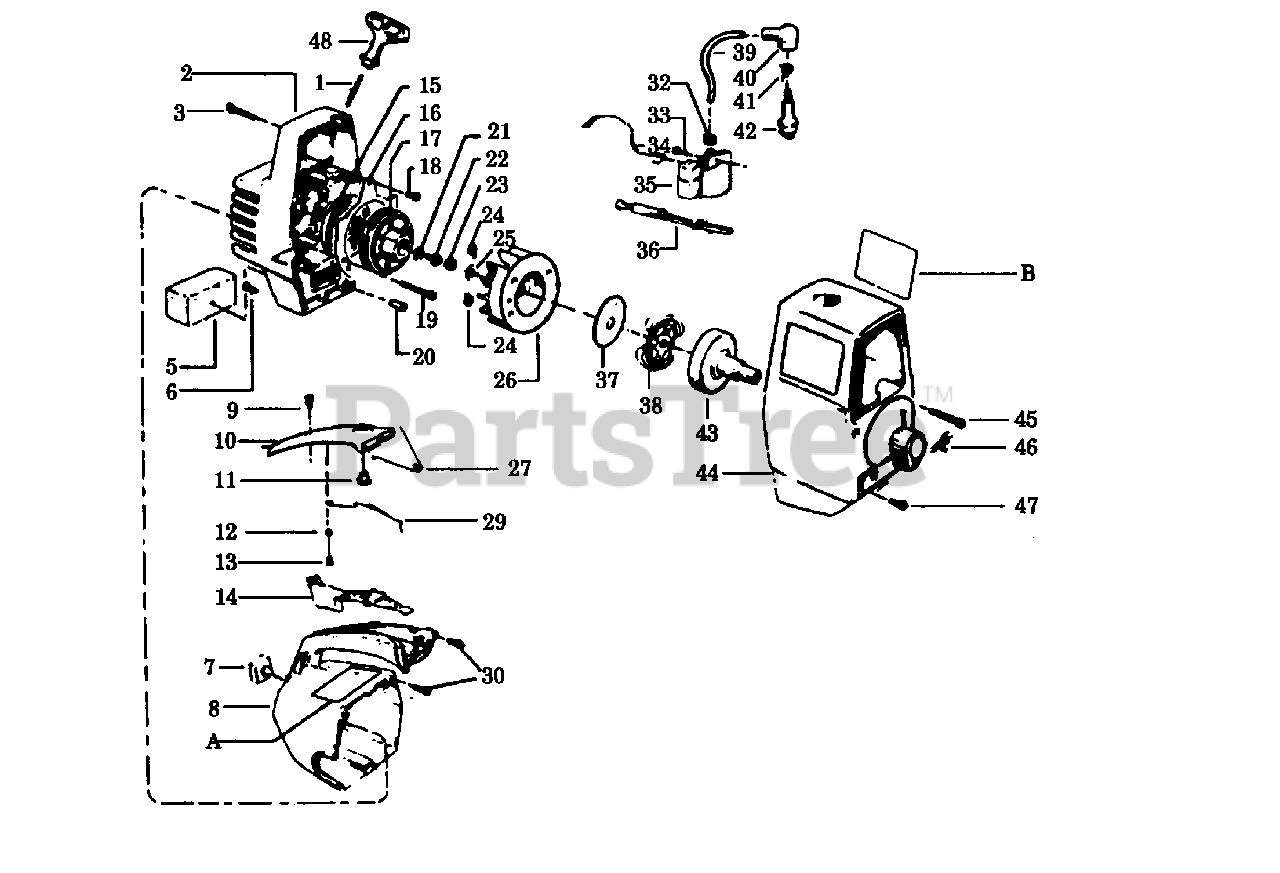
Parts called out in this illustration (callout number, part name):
1	Rope Kit
2	Fan Housing Kit
5	Air Filter
7	Fuel Tank Housing Bumper
8	Handle & Fuel Tank Housing
10	Handle Cover
11	Switch Button
12	Switch Washer
14	Throttle Trigger
15	Recoil Spring Starter
16	Air Baffle
17	Starter Pulley
20	Air Baffle Spacer
22	Screw
23	Flywheel Nut
24	Starter Dog Spring
26	Flywheel Ass'y.
27	Trigger Spring
29	Switch Spring
30	Screw
32	Plug Wire Grommet
33	Screw
34	Lead Wire Switch
35	Ignition Module Kit
36	Choke Knob
37	Clutch Washer Kit
38	Clutch Kit Ass'y. (Inc. Clutch Washer)
39	High Tension Lead Wire
40	Spark Plug Boot
41	Spark Plug Lead Connector
42	Spark Plug-CJ-14
43	Drum & Coupling Ass'y.
46	Pinch Clamp Bolt
48	Starter Handle
A	Starting Instruction Decal (Not a serviceable part)
B	Right- Model YP120
B	Right- Model YP120A
B	Left Model YP120
B	Left Model YP120A
